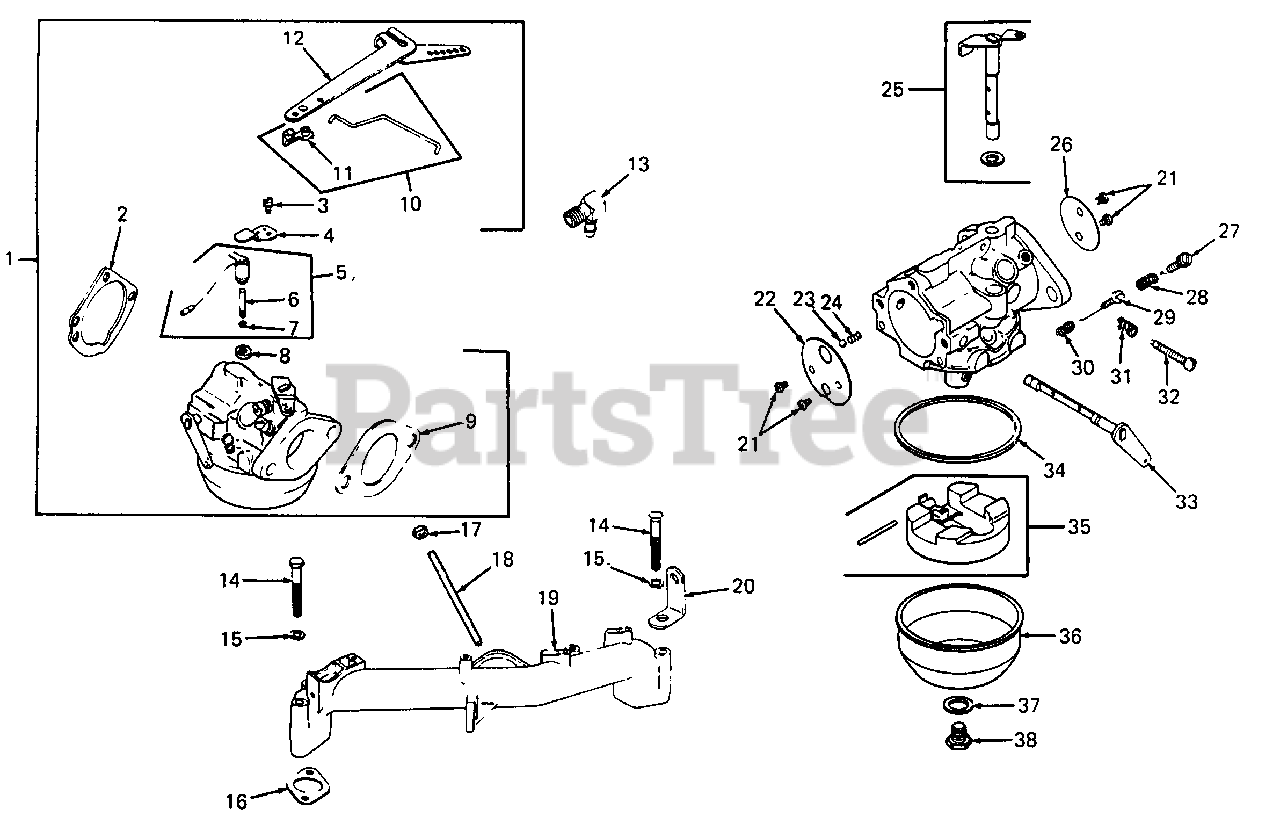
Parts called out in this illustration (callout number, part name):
1	Kit, Carburetor w/Linkage
2	Gasket, Air Cleaner Elbow
4	Bracket, Solenoid
5	Kit, Solenoid
6	Rod, Plunger
8	Gasket, Needle Seat
9	Gasket, Carburetor
10	Kit, Governor Linkage
11	Bushing, Governor Linkage
12	Arm, Governor
13	Connector, Hose
14	Screw, HC 5/16-18 X 2-3/4
15	Washer, Lock, 5/16
16	Gasket, Intake Manifold
17	Nut, Hex Jam, 5/16-18
18	Stud, 5/16-18 X 1
19	Manifold, Intake
20	Strap, Lifting
21	Screw, Throttle & Choke Plate
22	Plate, Choke
23	Ball, Choke Friction
24	Spring, Choke Friction
25	Shaft, Throttle w/Lever & Seal
26	Plate, Throttle
27	Needle, Idle Fuel Adj
28	Spring, Idle Fuel
29	Needle, Main Fuel
30	Spring, Main Fuel
31	Spring, Idle Speed
32	Screw, Idle Speed Adj
33	Lever, Choke
34	Gasket, Bowl
37	Gasket, Bowl Retainer Screw
38	Screw, Bowl Retainer
